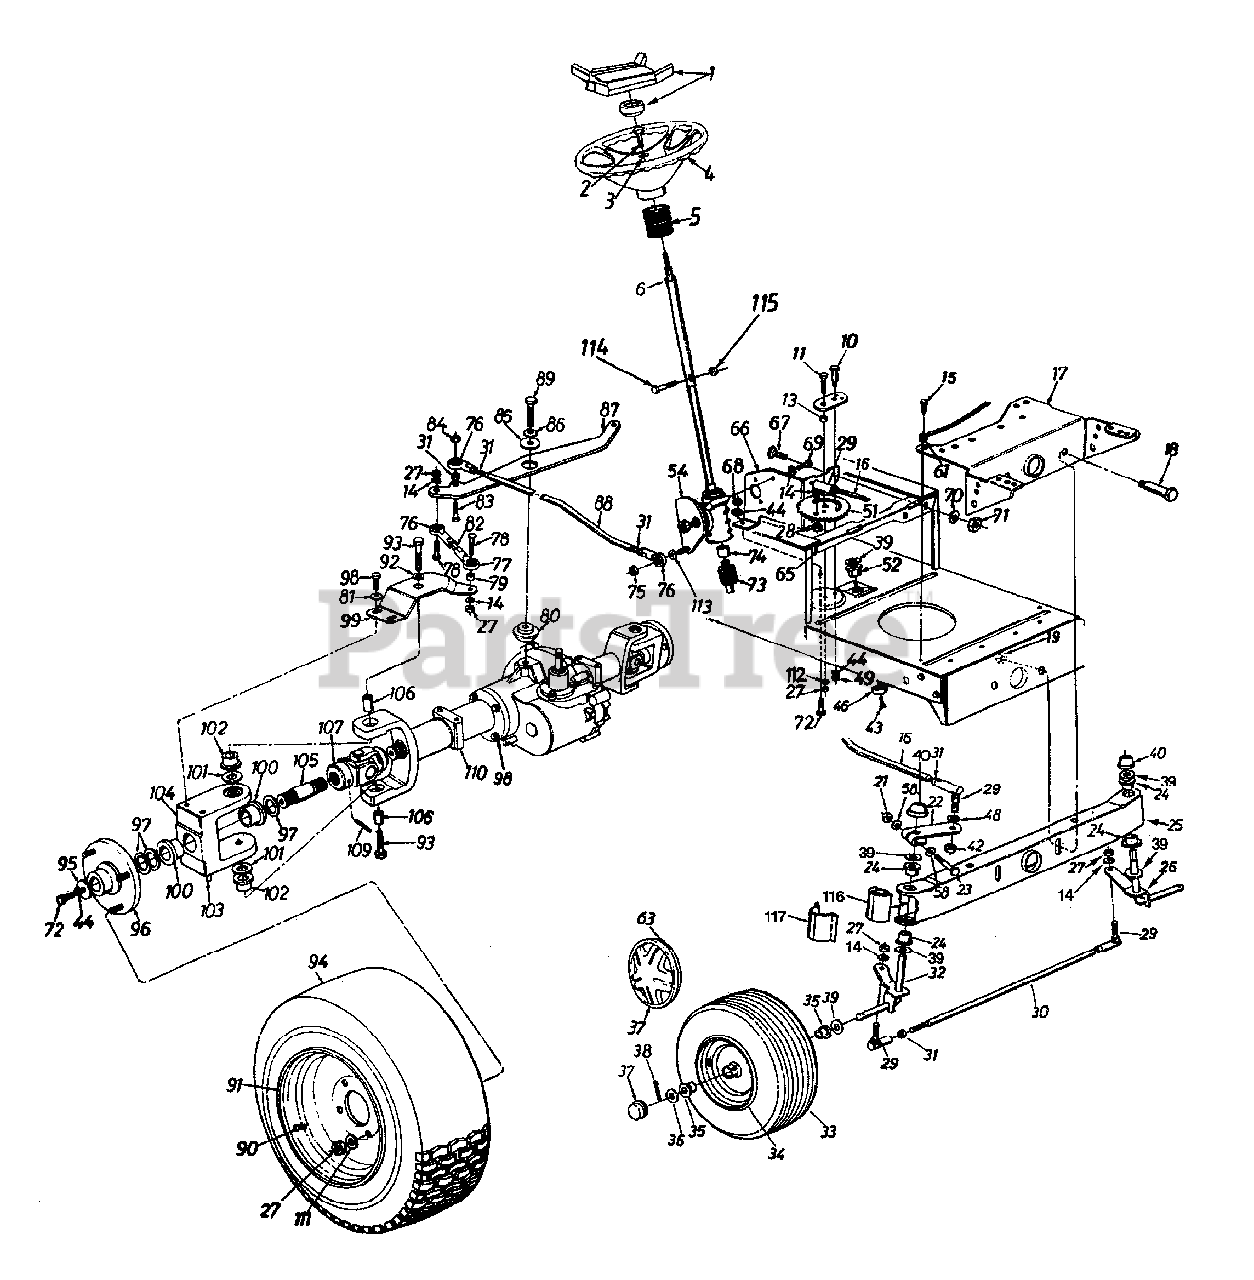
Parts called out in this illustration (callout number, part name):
1	Steering Wheel Insert
2	Hex Patch Bolt 5/16-18 x 1" Lg.
3	Belleville Wash. .345" I.D.
4	Steering Wheel (4 Spoke)
5	Steering Bellow
6	Upper Steering Shaft
10	Shoulder Bolt .437" Dia. x .35" Lg.
11	Hex Bolt 3/8-24 x 1.0" Lg. (Grade 5)
13	Spacer .380" I.D. x .625" O.D. x .227"
14	L-Wash. 3/8" I.D.
15	Hex Wash. Hd. Self-Tap Scr.
16	Steering Drag Link
18	Shoulder Bolt .498" Dia. x 2.04" Lg.
19	Hex L-Nut 3/8-16 Thd.
21	Hex Cent. L-Nut 5/16-24 Thd.
22	Steering Arm Front Axle
23	Hex Bolt 5/16-24 x 2.00" Lg. (Gr. 5)
24	Hex Flg. Brg. .634" I.D.
26	Front Axle Ass'y.-L.H.
27	Hex Nut 3/8-24 Thd.
28	Hex Jam Nut 3/8-24 Thd.
29	Ball Joint 3/8-24 Thd.
30	Tie Rod
31	Hex Jam Nut 3/8-24 Thd.
32	Front Axle Ass'y.-R.H.
35	Bearing
36	Fl-Wash. .635" I.D. x 1.59" O.D.
37	Front Hub Cap
38	Cotter Pin 1/8" Dia. x 1.25" Lg.
39	Fl-Wash. .640" I.D. x .24" O.D.
40	Push Cap
43	Pan Hd. Bolt 5/16-18 x .62"
44	L-Wash. 5/16" I.D.
48	L-Wash. 3/8" I.D.
49	Hex Nut 5/16-18 Thd.
51	Steering Gear Segment
52	Hex Flg. Brg. .634 I.D.
54	Steering Box Ass'y. Comp.
58	Wave Wash. .32" I.D. x .62"
61	Ext. L-Wash. 5/16" I.D.
63	Spring Clip
65	Horizontal Cross Bracket
66	Vertical Mounting Bracket
67	Hex Bolt 1/4-28 x .75" Lg.
68	Hex Nut 5/16-24 Thd.
69	Hex Bolt 3/8-16 x 1.0" Lg.
70	Bell-Wash. .265" I.D. x .75"
71	Hex Nut 1/4-28 Thd.
72	Hex Bolt 5/16-24 x .75" Lg.
73	Pinion Shaft
74	Steering Shaft Splined Coupler
75	Hex L-Nut 3/8-24 Thd.
76	Rod End 3/8-24 Thd.-R.H.
77	Rod End 3/8-24 Thd.-L.H.
78	Hex Bolt 3/8-24 x 1.5" Lg.(Gr. 5)
79	Spacer .38" I.D. x .625"
80	Shld. Spacer .51" I.D.
81	Bell-Wash. .38" I.D. x .88"
82	Tie Rod
83	Hex Bolt 3/8-24 x 1.25" Lg.
84	Hex Patch L-Nut 3/8-24 Thd.
85	Fl-Wash. .531" I.D. x 1.75"
86	Bell-Wash. .505" I.D. x 1.0"
89	Hex Bolt 1/2-13 x 1.5" Lg. (Gr. 5)
90	Air Valve
93	Hex Bolt 1/2-20 x 1.75" Lg.(Gr. 5)
95	Fl-Wash. .33" I.D. x 1.25"
96	Wheel Flange Ass'y.
97	Fl-Wash. 1.0" x 1.56"
98	Hex Bolt 3/8-24 x 1.25" Lg.
101	Fl-Wash. .76" I.D. x 1.5"
102	Flange Brg. 3/4" I.D.
103	Grease Fitting
104	Wheel Brg. Housing
105	Wheel Flange Ass'y
106	Pivot Sleeve
107	U-Joint
109	Grooved Roll Pin 1.0" Lg.
110	Axle Horn Ass'y.
111	Bell-Wash. .38" I.D. x .88"
112	Bell-Wash. .39" I.D. x 1.38"
113	Fl-Wash. .385" I.D. x .62"
114	Hex Bolt 1/4-20 x 1.31" Lg.
115	Hex Ins. L-Nut 1/4-20 Thd.
116	Pivot Bar End Cap
